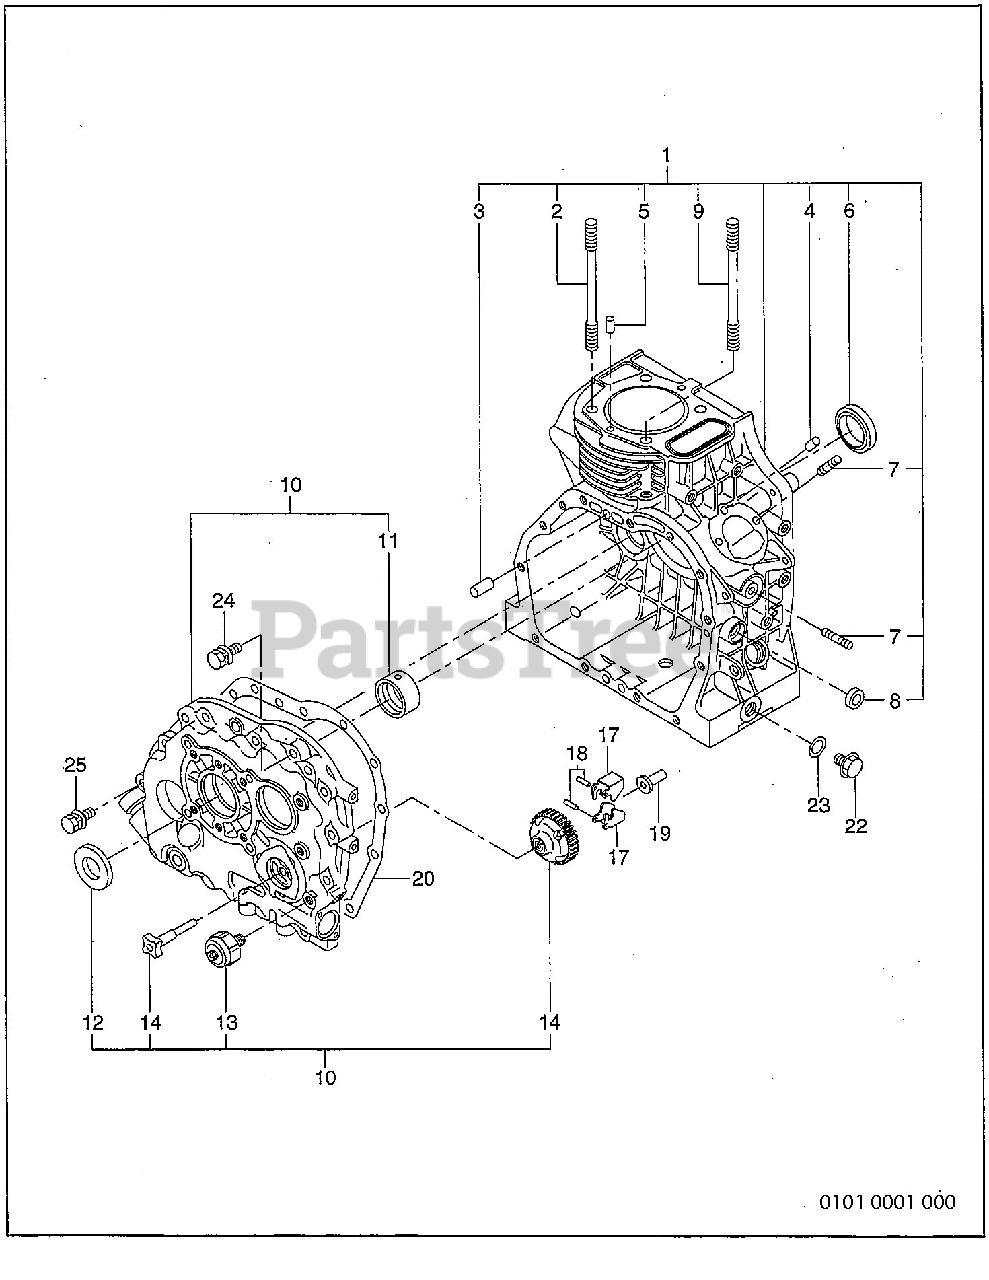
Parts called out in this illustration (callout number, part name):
1	CRANKCASE ASSY
6	OIL SEAL (30X48X8mm)
8	OIL SEAL (8X18X7mm)
10	MAIN BEARING COVER ASSY
11	MAIN BEARING, STD.
11	MAIN BEARING, under size 0.25mm
11	MAIN BEARING, under size 0.50mm
12	OIL SEAL (30X45X8mm)
13	SWITCH ASSY, oil presuure
14	GOVERNOR GEAR SHAFT SET
19	GOVERNOR SLEEVE
20	GASKET, bearing cover
24	BOLT and WASHER ASSY
25	BOLT and WASHER ASSY
